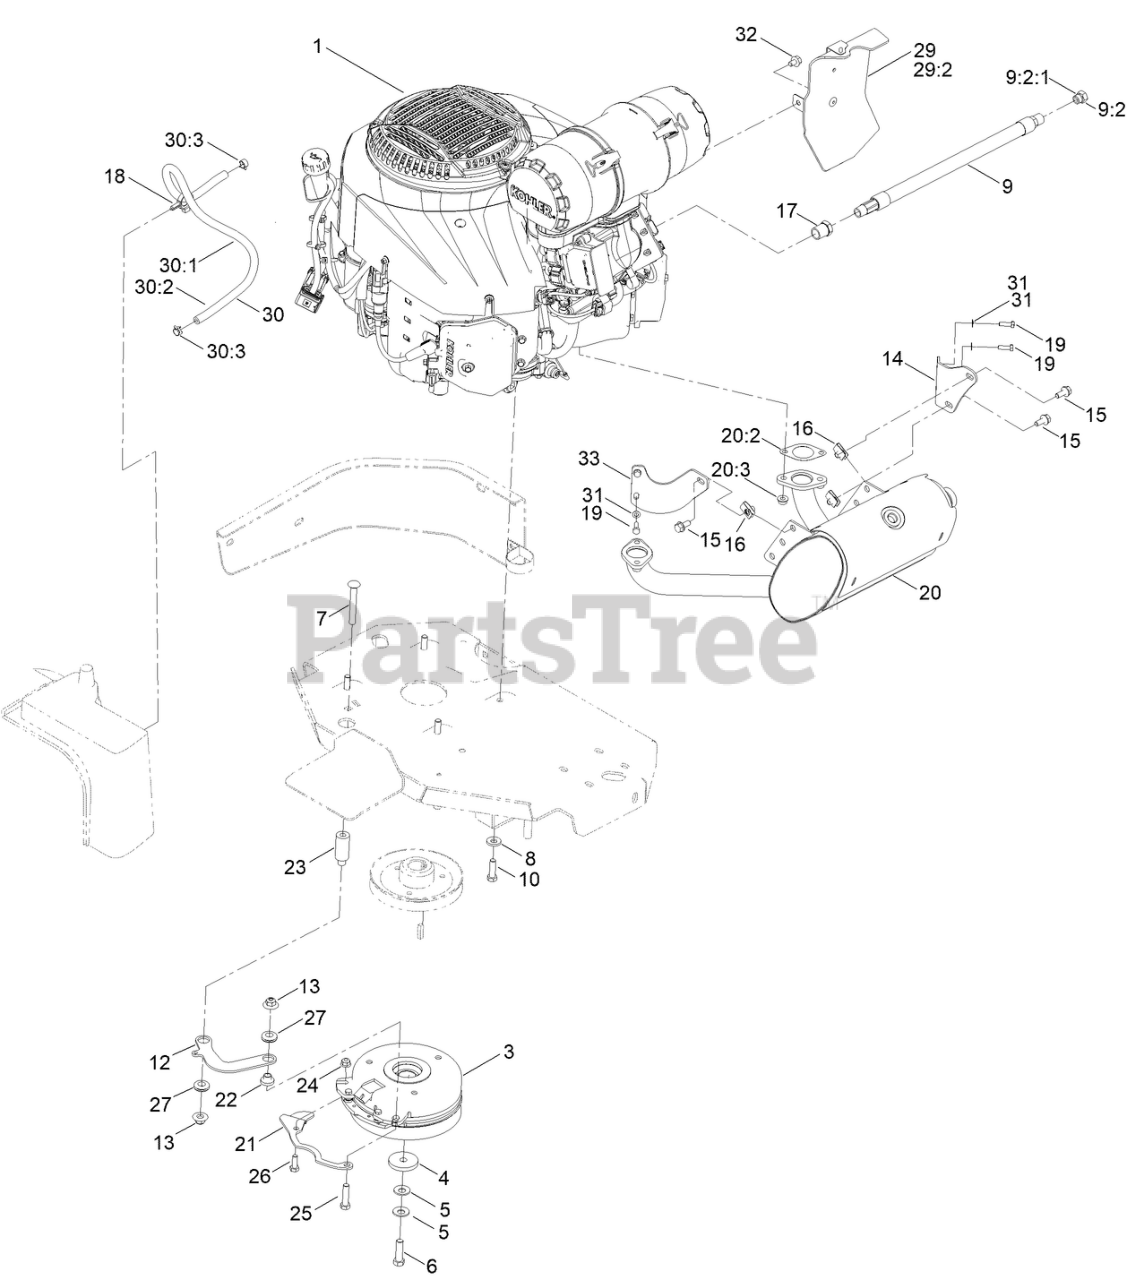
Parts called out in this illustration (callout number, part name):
3	CLUTCH KIT
4	WASHER-CLUTCH
5	WASHER-SPRING
6	SCREW-HH, W/LOCTITE
7	SCREW-CARR
8	WASHER-BELLEVILLE
9	OIL DRAIN HOSE ASM
9:2	PLUG-HH
9:2:1	O-RING
10	SCREW-HH
12	LINK-ANCHOR, CLUTCH
13	NUT-FLANGE, NI
14	BRACKET-MUFFLER
15	SCREW-HHF
16	NUT-U
17	BUSHING
18	CLAMP-HOSE
19	SCREW-HH
20	MUFFLER-940-980 KOH EFI
20	MUFFLER KIT
20:2	GASKET-EXHAUST
20:3	NUT-FLANGE, LOCK
21	BELT-GUIDE
22	SPACER
23	SPACER
24	NUT-HF, NI
25	SCREW-HH
26	SCREW-HH
27	GROMMET-RUBBER
29	BAFFLE KIT
29:2	SCREW-HWH
29:2	SCREW-HHF
30	FUEL LINE ASM
30:1	HOSE-FUEL
30:2	SLEEVE, THERMAL
30:3	CLAMP-HOSE
31	WASHER-SPRING
32	SCREW-HHF
33	BRACKET-MUFFLER, FRONT
